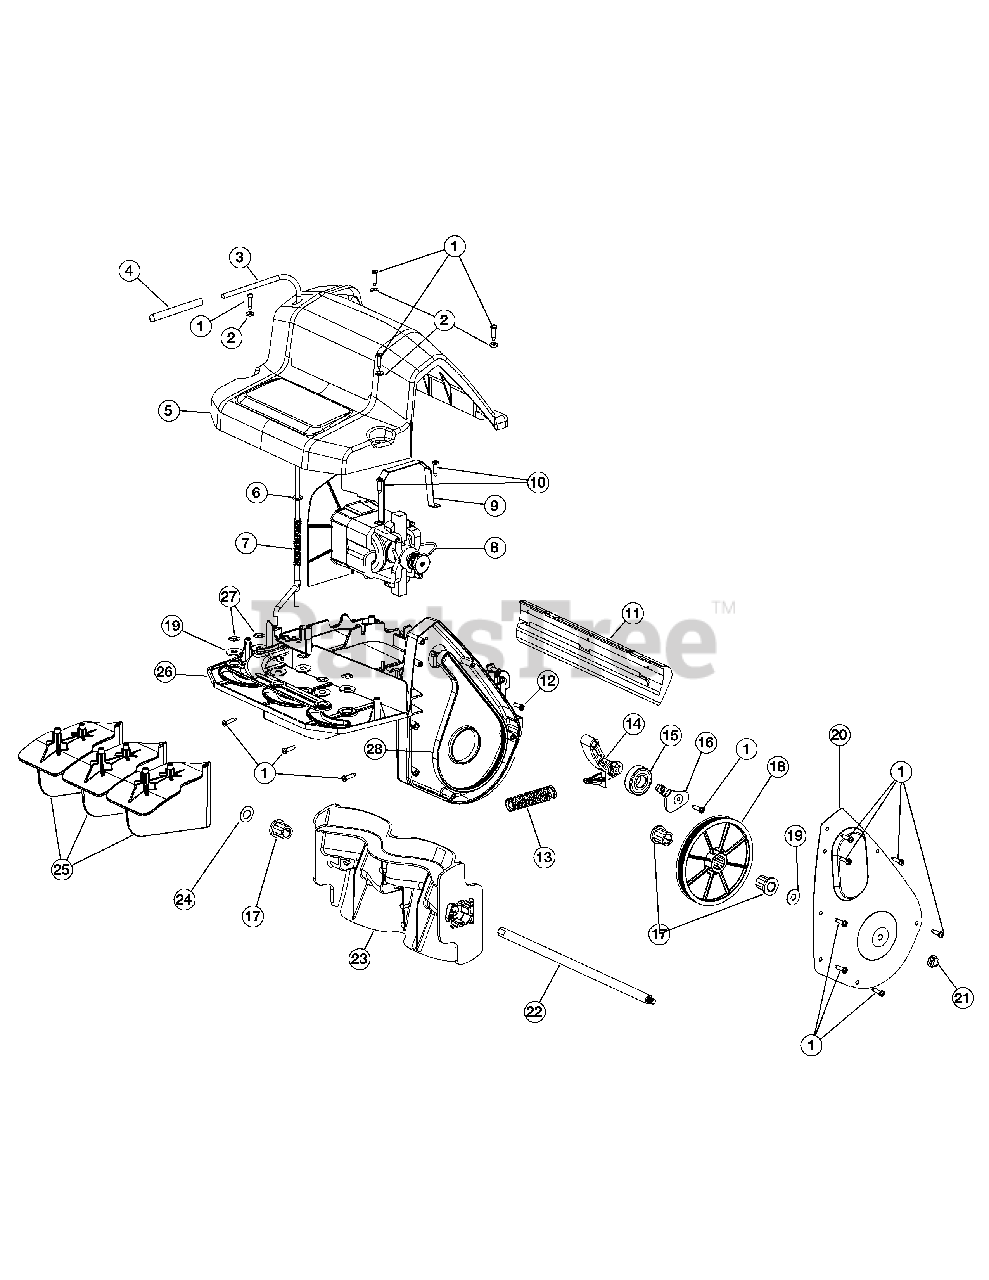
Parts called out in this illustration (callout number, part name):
3	Vane Control Handle (includes 4)
4	Grip
6	Washer
7	Spring
8	Motor Assm w/Baffle, Fan & Pulley
9	Motor Strap
10	Screw
11	Scraper
13	Spring
14	Idler Arm
15	Ball Bearing
16	Keeper
17	Flange Bearing
18	Driven Pulley
19	Washer
20	Belt Case Cover
21	Flange Lock Nut
22	Axle Auger
26	Snow Thrower Housing
27	Push Nut
28	Drive Belt
